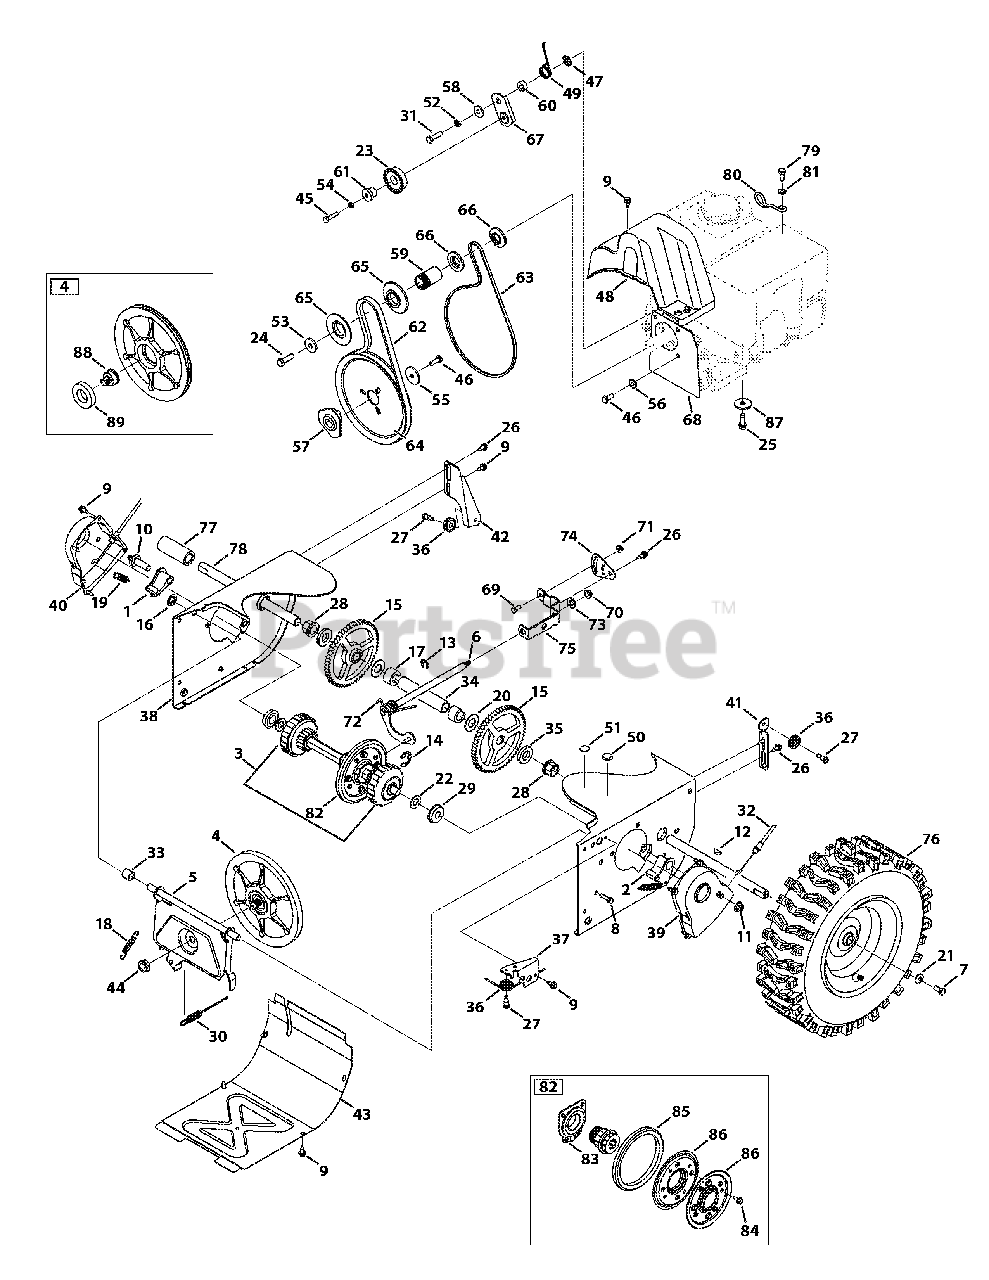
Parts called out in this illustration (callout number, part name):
1	Dogg Assembly, RH
2	Dogg Assembly, LH
3	Drive Shaft Assembly
4	Friction Wheel Disc Assembly
5	Friction Wheel Support
6	Rod Shift Assembly
7	Hex Head Screw, 5/16-24 x .750
8	Screw, 1/4-20 x 1.000
9	Screw, 1/4-20 x .625
10	Actuator Shaft
11	Nut, Flangelock, 3/8-16
12	Hi-Pro Key, 3/16 x 3/4 DIA
13	E-Ring
14	Retainer Ring
15	Gear, 56T
16	Nut, Speed, .500
17	Spacer, .76ID x .75 LG
18	Extension Spring, .380 x 2.500
19	Extension Spring, .500 x 1.71
20	Washer, Flat, .76 x 1.49 x .06
21	Washer, Bell, .340 x .872 x .060
22	Washer, Flat, .58 x 1.125 x .08
23	Pulley Assembly
24	Hex Head Screw, 3/8-24 x 1.25
25	TT Sems Screw, 3/8-16 x 1.000
26	Screw, Shoulder, .368 x .113 x 1/4-20
27	C Screw, Shoulder, .340 x .335 x 1/4-28
28	Hex Flange Bearing, .75 ID
29	Ball Bearing, .5625 x 1.375 x .4375
30	Drive Clutch Cable, 44.955 LG
31	Hex Head Screw, 5/16-24 x 1.25
32	Steering Cable
33	Spacer, .508 ID x .75O OD x .68
34	Axle Support Tube
35	Spacer, Axle
36	Roller Cable
37	Auger Cable Guide Bracket
38	Wheel Drive Frame
39	Shaft Retainer, LH
40	Shaft Retainer, RH
41	Auger Clutch Cable Guide Bracket
42	Drive Clutch Cable Guide Bracket
43	Frame Cover
44	Nut, Flange, 5/8-18
45	TT Screw, 1/4-20 x 1.250
46	Hex Head Screw, 5/16-24 x .875
47	Nut, Push-On, .25 DIA
48	Belt Cover
49	Spring, Torsion, .850 ID x .333 LG
50	Plug, 3/8 ID
51	Plug, 1/2 ID
52	Washer, Lock, 5/16
53	Washer, Flat, .406 x 1.25 x .157
54	Washer, Lock, 1/4
55	Washer, Flat, .34 x 1.50 x .150
56	Shoulder Spacer
57	Pulley Adapter, .75 DIA
58	Spacer, Shoulder, .3175 x .500 x .0975
59	Spacer, .875ID x 1.185OD
60	Spacer, .340 x .750 x .330 LG
61	Spacer, Shoulder, .260 x .785 x .538
62	Belt, .500 x 37.00 LG
63	V Belt, 3/8 x 35.68"
64	Auger Pulley, 8.1 x .5
65	Pulley, Half, 4L-V x 2.600 OD
66	Pulley, Half, 3/8-V x 1.7160 OD
67	Drive Idler Bracket
68	Cover Plate
69	Hex Head Screw, 1/4-20 x .620
70	Nut, Flangelock, 5/16-18
71	Nut, Flangelock, 1/4-20
72	Spring, Torsion, .750ID x .968LG
73	Washer, Flat, .469 x .875 x .105
74	Speed Selector Pivot Bracket
75	Speed Selector Shift Bracket
76	Wheel, LH
76	Wheel, RH
77	Spacer, 1.25OD x .75ID x 3.00 LG
78	Axle, .75OD x 11.12 LG
79	Hex Head Screw, 1.25 x 20
80	Cable Guide
81	Washer, Flat, .330 x .630 x .0365
82	Friction Wheel Assembly
83	Bearing Assembly, Friction Wheel
84	Screw, 1/4-14 x .625
85	Friction Wheel, 5.5 OD
86	Friction Wheel Plate
87	Washer, Flat, .38 x 1.38 x .125
88	Friction Pin, Disc Bearing
89	Ball Bearing, 30 x 55 x 13
